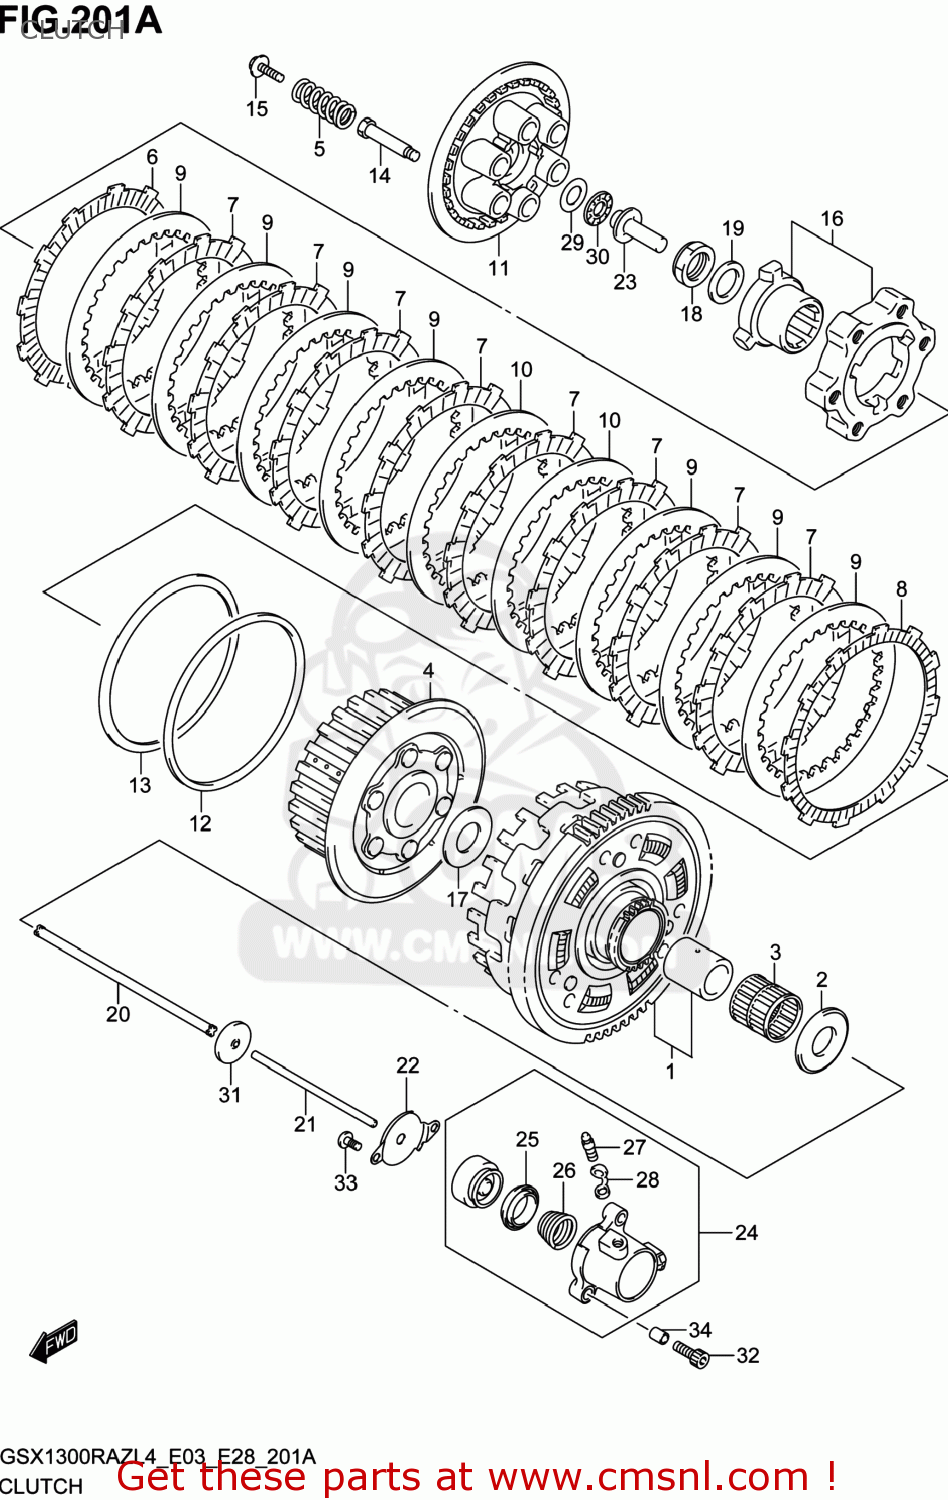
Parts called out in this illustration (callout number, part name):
1	GEAR ASSY,PRI DRIVEN
2	WASHER(25X54X2.4)
3	BEARING(35X40X39.8)
4	HUB,CLUTCH SLEEVE
5	SPRING,CLUTCH
6	PLATE,CLUTCH DRIVE NO.2 (NAS)
7	PLATE,CLUTCH DRIVE NO.1 (NAS)
8	PLATE,CLUTCH DRIVE NO.3 (NAS)
9	PLATE,CLUTCH DRIVEN NO.1(T:2.0 (NAS)
10	PLATE,CLUTCH DRIVEN NO.2(T:2.3 (NAS)
11	DISC,CLUTCH PRESSURE
12	SEAT,WAVE WASHER
13	WASHER,CLUTCH PLATE WAVE
14	BOLT,CLUTCH SPRING SUPPORT
15	BOLT,CLUTCH SPRING
16	CAM SET,CLUTCH
17	WASHER(25X50X2.5)
18	NUT
19	WASHER
20	ROD,CLUTCH
21	ROD,CLUTCH PUSH,L
22	COVER,CLUTCH RELEASE CYLINDER
23	PIECE,CLUTCH PUSH
24	CYLINDER,CLUTCH RELEASE
25	CUP
26	SPRING
27	BLEEDER
28	CAP,BLEEDER
29	WASHER(15.5X28X1)
30	BEARING(15X28X2)
31	SEAL,OIL(6X34X5.5)
32	BOLT
33	SCREW
34	PIN
